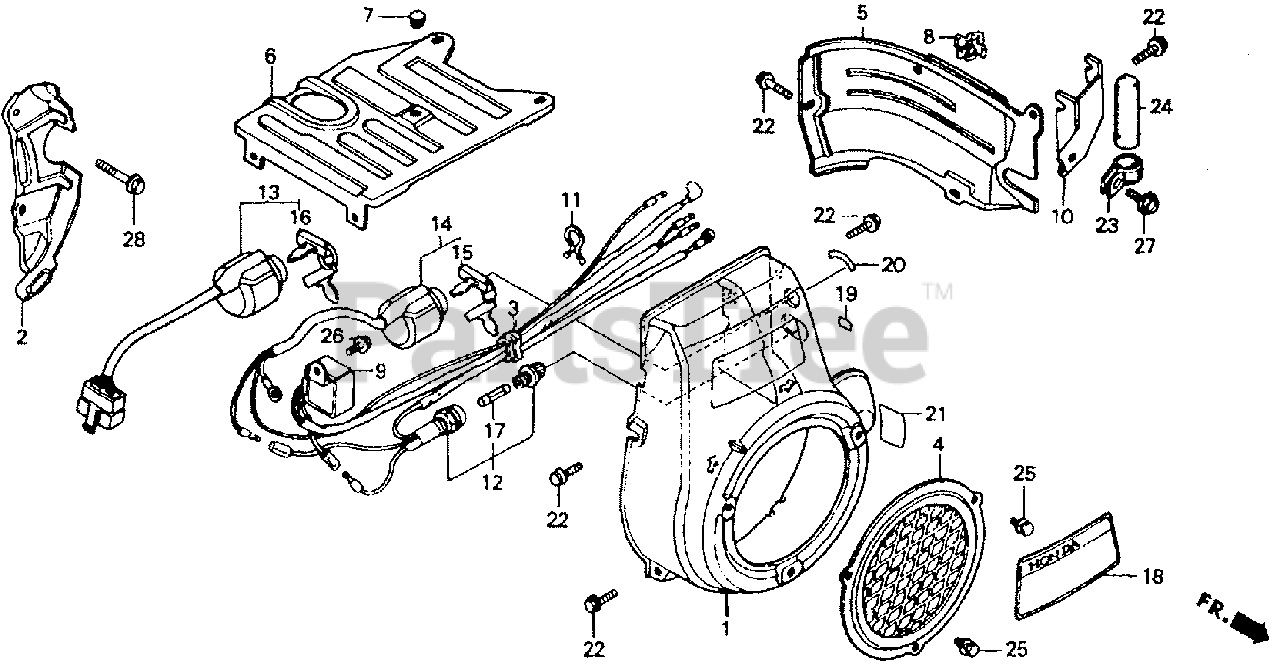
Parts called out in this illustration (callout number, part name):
1	COVER, FAN *R8* (BRIGHT RED)
2	PLATE, SIDE
3	GROMMET, SWITCH WIRE
4	PROTECTOR, FAN COVER *R8* (BRIGHT RED)
5	SHROUD *R8* (BRIGHT RED)
6	COVER, TOP *R8* (BRIGHT RED)
7	GROMMET, TOP COVER
8	CLIP, IGNITION WIRE (8MM)
9	RECTIFIER, SILICON
10	STAY, CLAMP
11	CLAMP, CABLE
11	CLIP, PURSE LOCK (11MM)
12	HOLDER, FUSE (1.5A) (NOT AVAILABLE)
13	SWITCH ASSY., COMBINATION
14	SWITCH ASSY., COMBINATION
15	KEY
16	KEY
17	FUSE (1.5A) (NOT AVAILABLE)
18	EMBLEM (ENGLISH/FRENCH/SPANISH)
19	MARK, FUSE (1.5A)
20	MARK, ENGINE SWITCH
21	MARK, OIL CAUTION
22	BOLT, FLANGE (6X12) (CT200)
23	CLIP, CORD
24	TUBE, CORD (25MM)
25	BOLT-WASHER (6X10)
26	BOLT, FLANGE (6X10)
27	BOLT, FLANGE (6X12)
28	BOLT, FLANGE (8X20)
